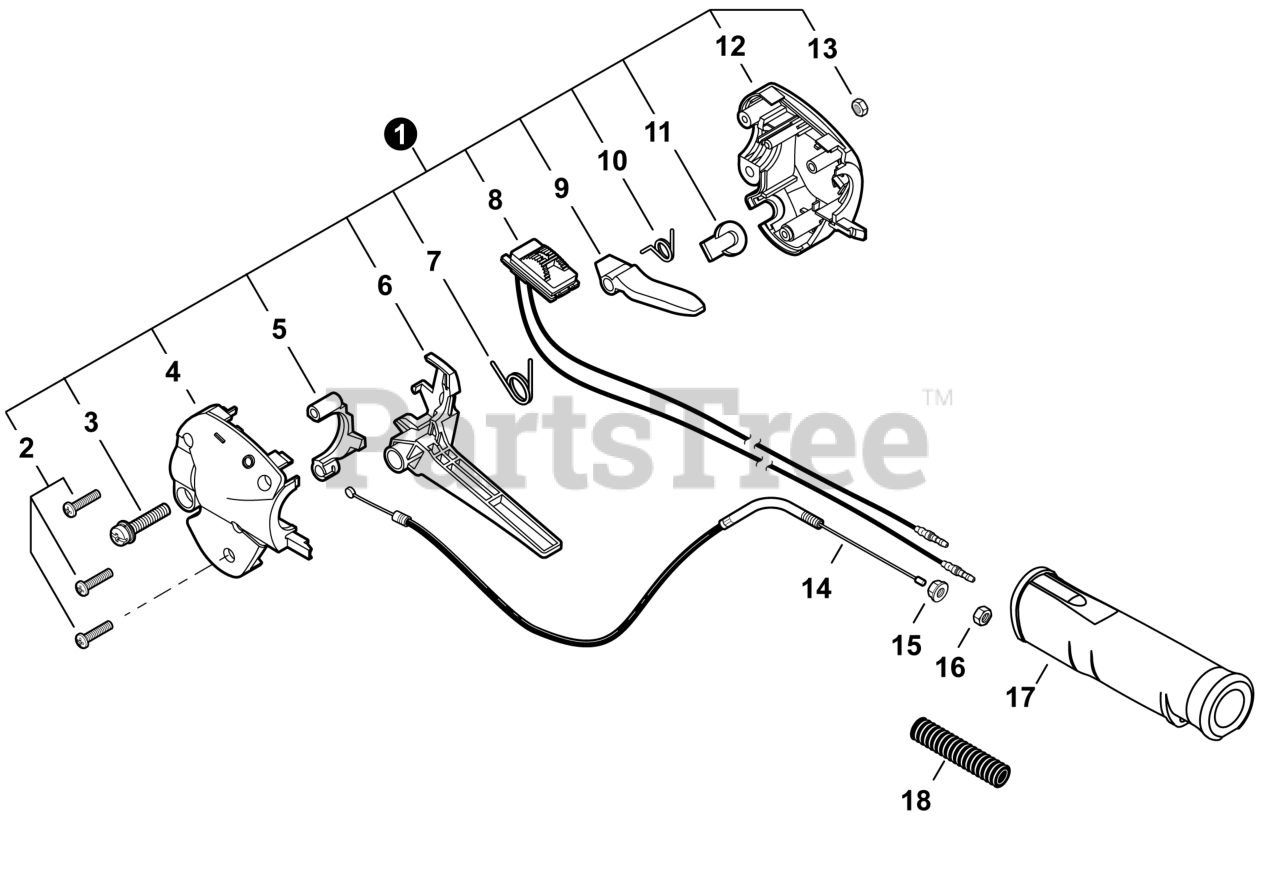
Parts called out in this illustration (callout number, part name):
1	THROTTLE CONTROL ASSY
3	BOLT, TORX 5x16
4	CONTROL HANDLE - LEFT
5	LOCKOUT, THROTTLE
6	TRIGGER, THROTTLE
7	SPRING, THROTTLE RETURN
8	SWITCH, ON-OFF
9	LEVER, THROTTLE LOCKOUT
10	SPRING, THROTTLE LOCKOUT
12	CONTROL HANDLE - RIGHT
14	CABLE, THROTTLE
15	NUT, FLANGE M6
17	GRIP, HANDLE
18	TUBE, PLASTIC PROTECTIVE
